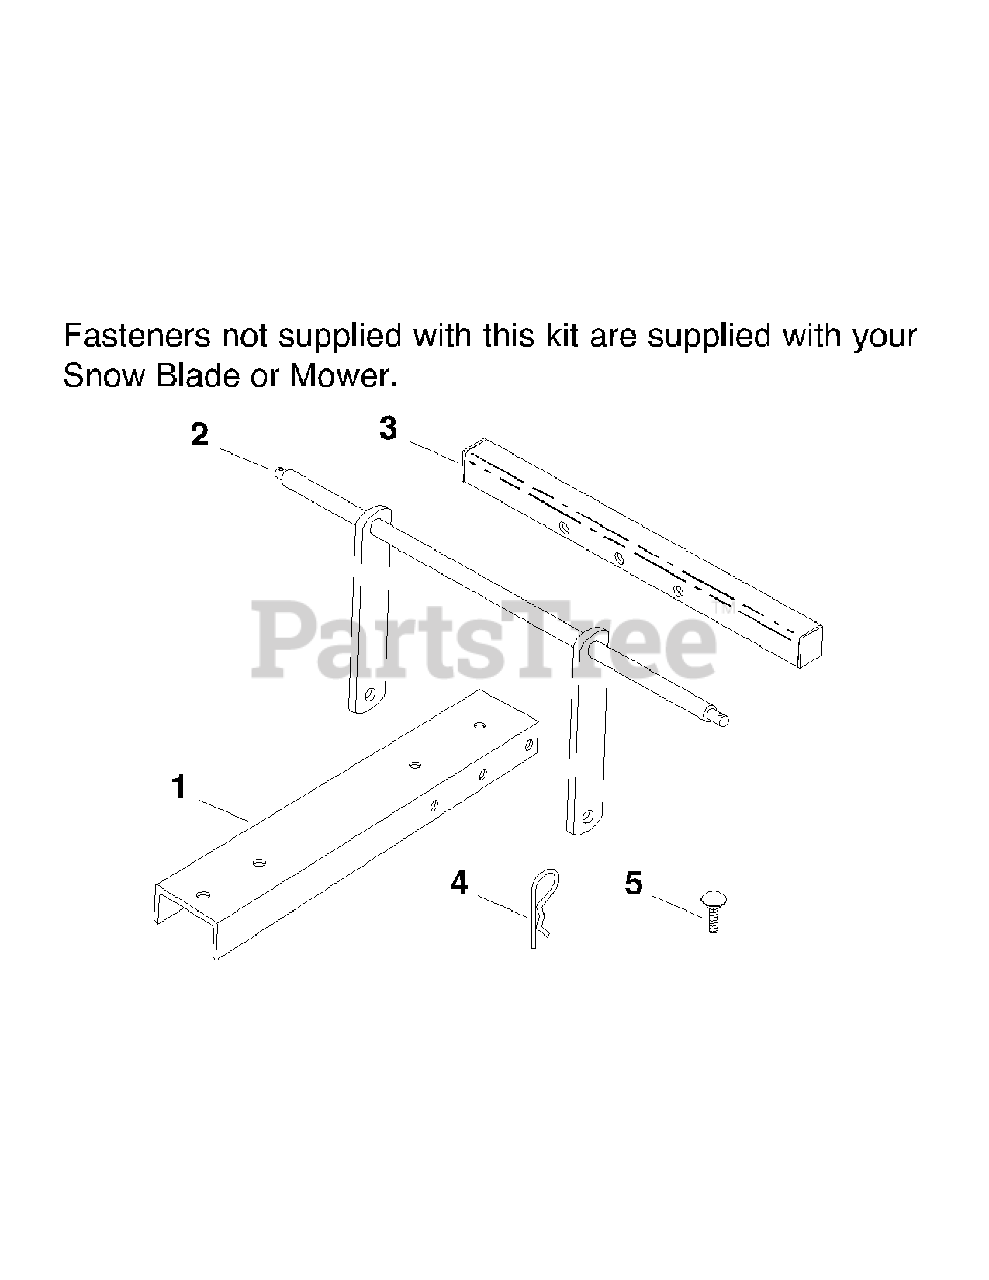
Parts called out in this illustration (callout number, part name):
1	Rear Push Bar
2	Lift Assembly
3	Guide Bracket Mounting Assem.
4	Hairpin Cotter, 5/32"
5	Carriage Bolt, 3/8-16 x 7/8"
